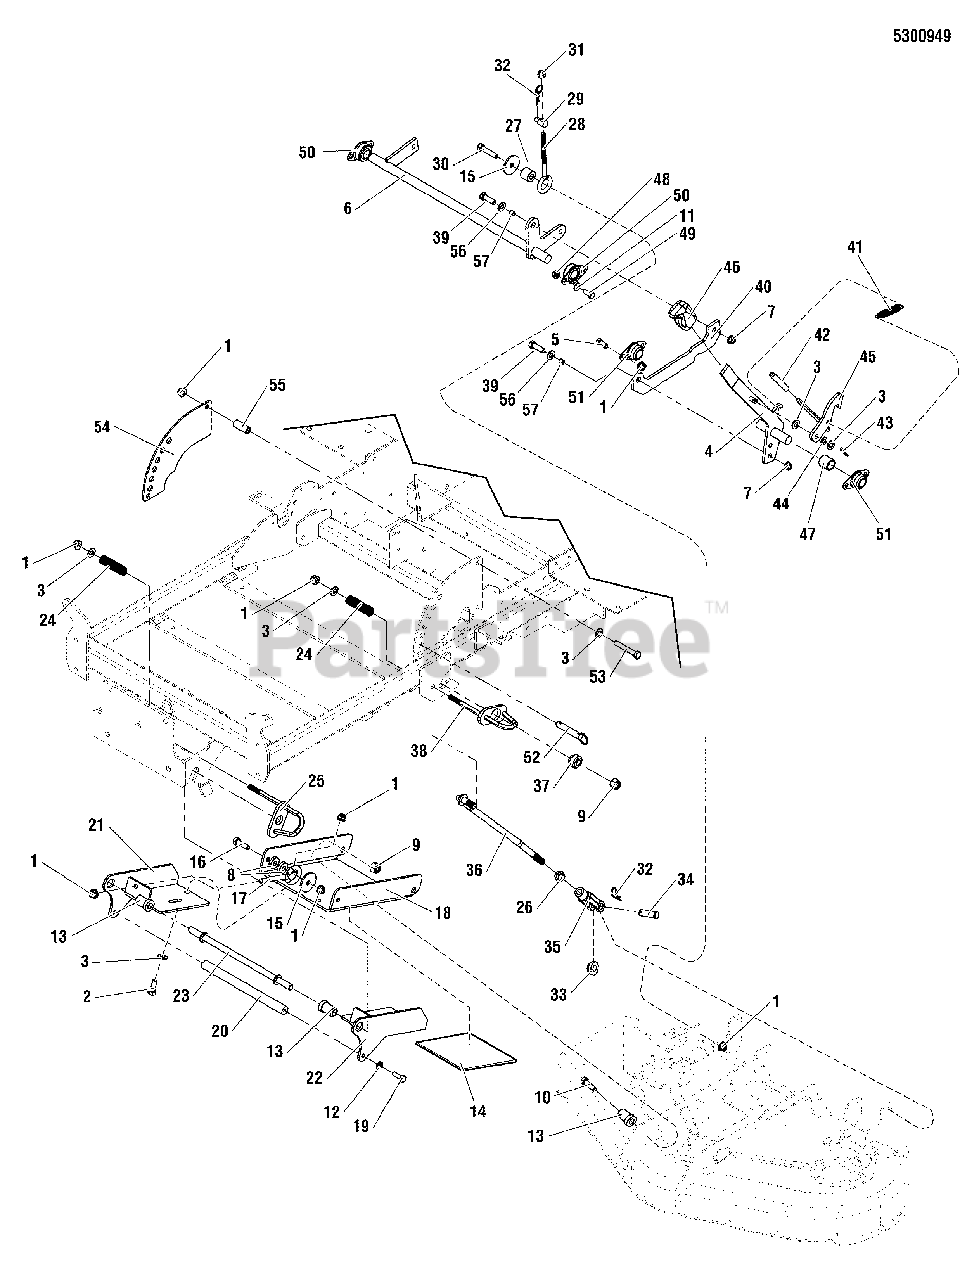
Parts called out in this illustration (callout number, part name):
1	NUT, 3/8-16 HEX NYLOCK FLANGE
2	BOLT, 3/8-16 X 1 GD5 YZ
3	WASHER, 3/8 SAE
4	WELD, HANDLE, DECK LIFT - ORG
5	BOLT, 3/8-16 X 3/4 GD5 YZ
6	WELD, SHAFT, REAR DECK LIFT - ORG
7	NUT, 3/8-16 HEX NYLOCK FLANGE
8	SPACER, .39 X 1.00 X .25
9	NUT, 1/2-20 HEX NYLON LOCK
10	BOLT, 1/2-20 X 2-1/2" GD5 YZ
11	WASHER, 5/16 SAE
12	WASHER, 5/16 LOCK YZ
13	SPACER, .53 X 1.00 X 1.00
14	SAFETY WALK, 4.50 X 3.50
15	WASHER, .41 X 1.75 X .14
16	BOLT, 3/8-16 X 1-1/4 GD5
17	EYE BOLT, 3/8-16 X 5", 1 EYE
18	PLATE, DECK HANGER SUPPORT - ORG
19	BOLT, 5/16-18 X 1 GD5 YZ
20	SHAFT, HANDLE, DECK MOUNT
21	WELD, DECK HANGER, RH - ORG
22	WELD, DECK HANGER, LH - ORG
23	SHAFT, HANGER
24	SPRING, COMPRESSION
25	WELD, QUICK RELEASE HANDLE - ORG
26	NUT, 1/2-20 HEX JAM
27	SPACER, .39 X 1.00 X .88
28	EYE BOLT, 3/8-16 X 6, 3.0 THRD, 1 EYE
29	ADJUSTER, BRAKE LINKAGE
30	BOLT, 3/8-16 X 1-3/4 GD5
31	NUT, 3/8-16 HEX NYLON LOCK
32	PIN, HAIR, .0915 X 1-7/8
33	BUSHING, DECK SUPPORT
34	PIN, CLEVIS, 1/2 X 1 1/2, YZP
35	CLEVIS, 1/2-20, STEEL
36	ROD, DECK LIFT LINKAGE
37	BUSHING, REAR QUICK TACH
38	WELD, QUICK RELEASE HANDLE, REAR - ORG.
39	BOLT, 3/8-16 X 1-1/4" GD5
40	LINK,DECK LIFT SHAFT
41	SPRING, EXTENSION
42	COVER, VINYL HANDLE
43	PIN, COTTER, 1/8" X 3/4
44	WASHER,WAVE,M10
45	WELD, DECK LOCK
46	GRIP, BLACK FLEXIBLE
47	SPACER, .76 X 1.00 X 1.00
48	NUT, 5/16-18 HEX NYLOCK FLANGE
49	BOLT, 5/16-18 X 3/4 GD5
50	BEARING, BRONZE FLANGE, 3/4"
51	BEARING, BRONZE FLANGE, 3/4
52	HITCH PIN ASSEMBLY, 1/2" X 2.50"
53	BOLT, 3/8-16 X 2-1/2 GD5 YZ
54	PLATE, DECK HEIGHT- INNER -ORG
55	SPACER, .39 X .63 X 1.50
56	WASHER, 3/8 SAE
57	SPACER, .38 X .50 X .38, YZ
